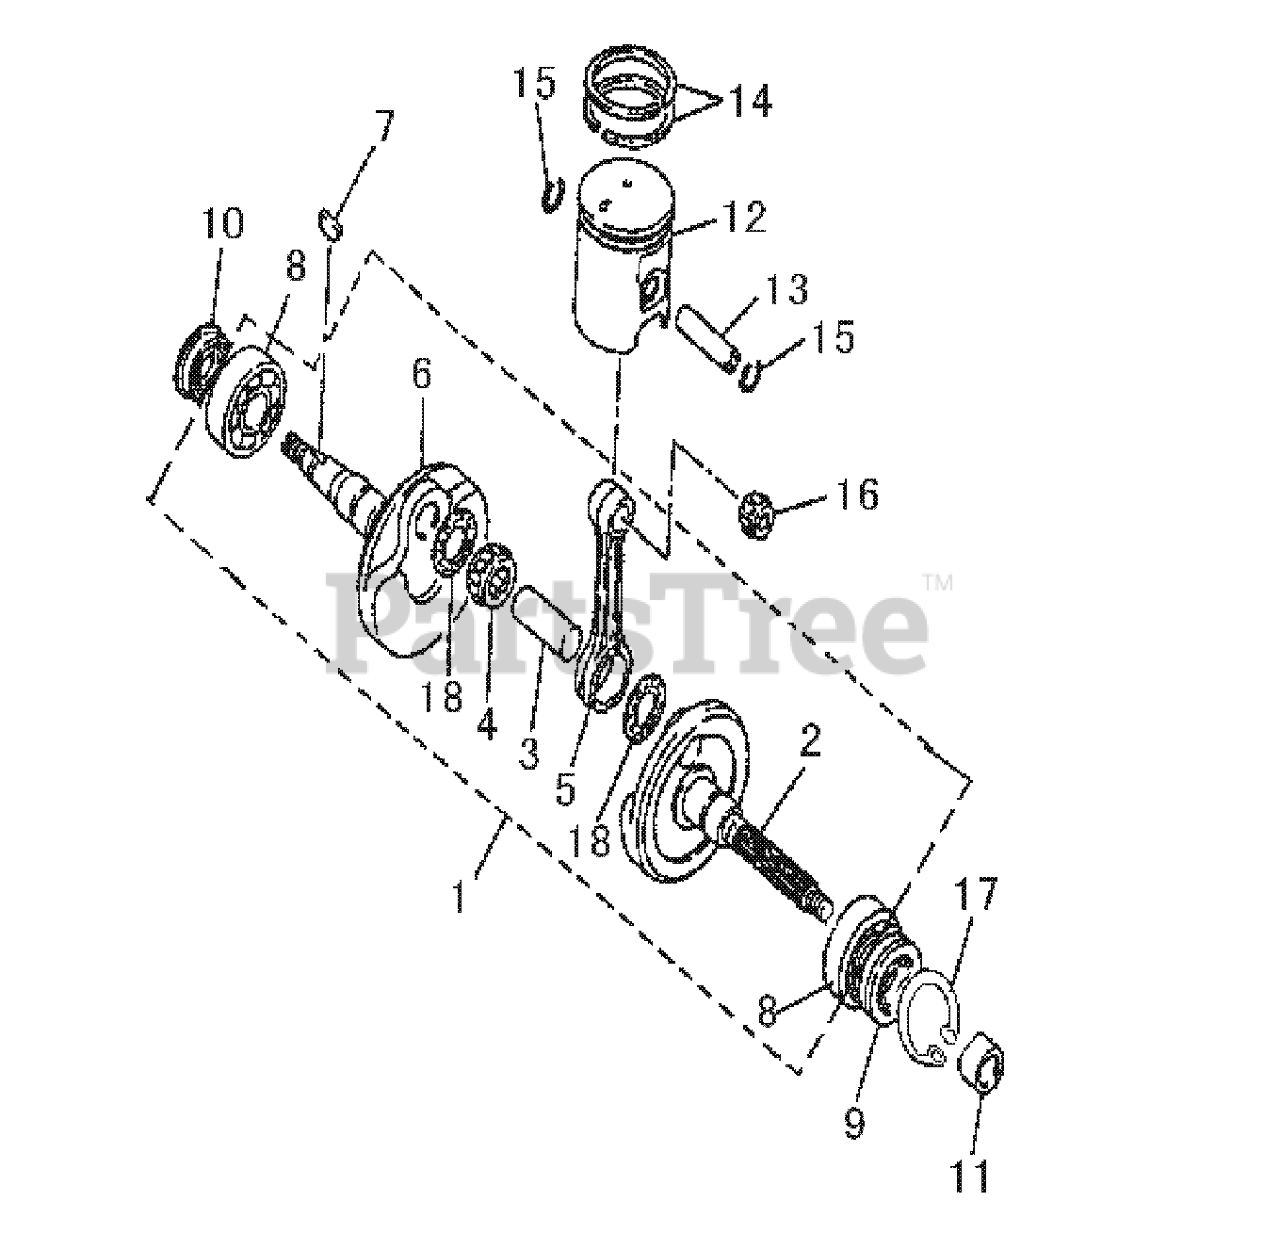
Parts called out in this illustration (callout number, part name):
1	CRANKSHAFT, ASSY
2	CRANKSHAFT, LH
3	CRANK PIN
4	NEEDLE BEARING
5	CONNECTING SHAFT
6	CRANKSHAFT, RH
7	WOODRUFF KEY
8	NEEDLE BEARING
9	OIL SEAL
10	OIL SEAL ASSY
12	PISTON ASSY
13	PISTON PIN
14	PISTON RING ASSY
15	CIRCLIP
16	NEEDLE BEARING
17	CIRCLIP
18	CONNECTING ROD WASHER
